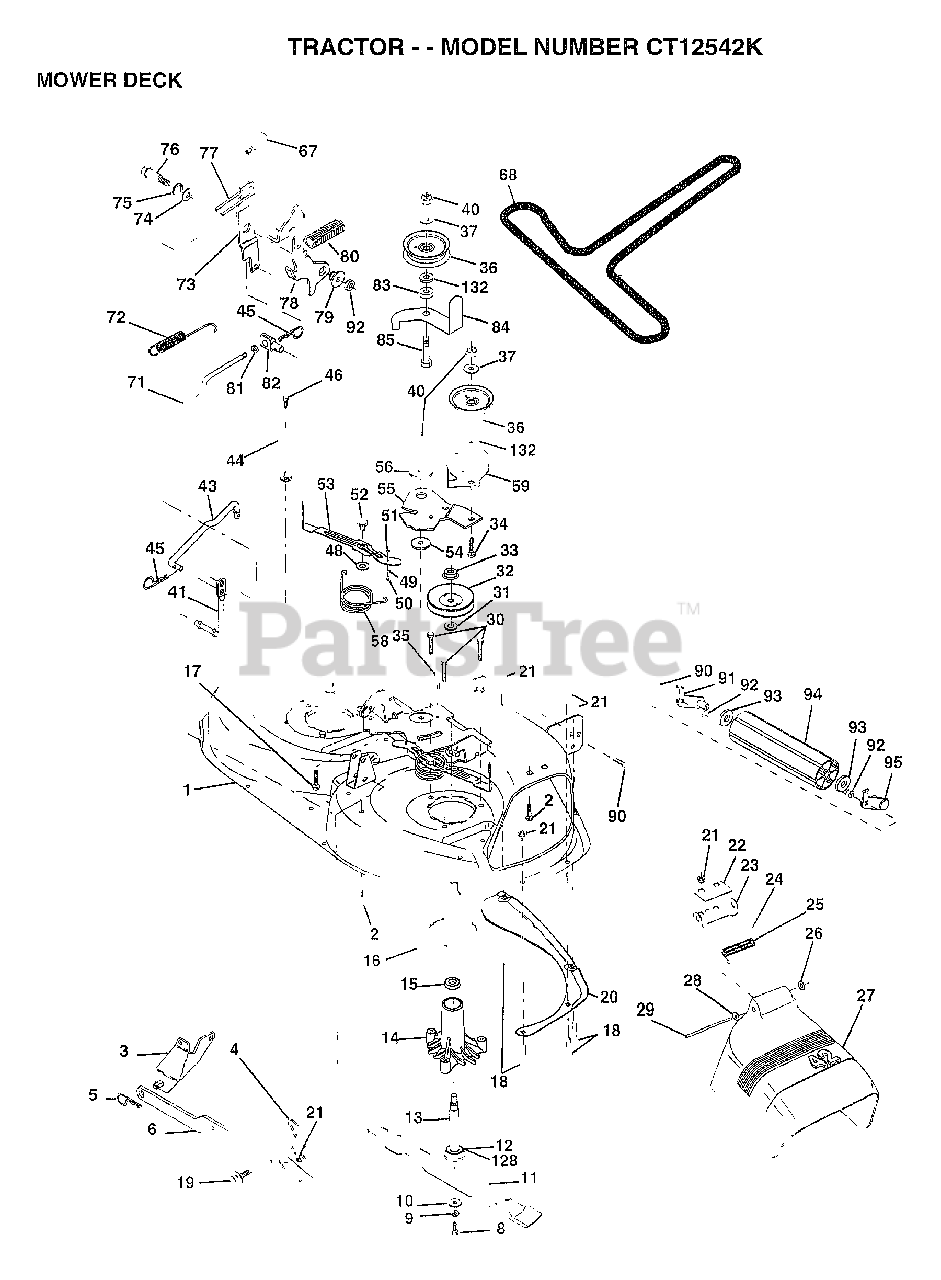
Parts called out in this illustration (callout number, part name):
1	DECK.WELD.42.
2	BOLT
3	BRKT ASM SWAY BAR
4	BRKT DECK SW BAR
8	BLADE BOLT
10	WASHER.HARD.BLADE
11	"BLADE.42"" HIPERF"
12	BEARING.BALL
14	HSG ASM MANDREL
15	BEARING
16	STRIPPER RND MWR
17	BOLT RDHD 3/8-16
18	BOLT
19	BOLT SHD 5/16-18
22	STIFFENER BRKT
23	DEFLECTOR BRKT
24	CAP-SLEEVE LT
25	SPRING TORSION
26	NUT PUSH M
27	DEFLECTOR.SHIELD
28	WASHER
29	HINGE ROD
31	WASHER
32	PULLEY.MANDREL.42
34	BOLT
35	XMAS TREE FASTNER
36	FLAT IDLER PULLEY
37	WASHER
41	PIVOT ROD
43	ROD CLUTCH W/NIBS
44	GUARD MAND LH BLK
46	SCREW.1/4-20X5/8
48	RETAINER M
48	HARD SMALL WASHER
49	ROLLER ASM-CAM
50	SHOULDER BOLT
51	LOCKNUT
52	BOLT.SHLD.5/16-18
53	BRAKE PAD ARM ASM
54	HARDENED WASHER
55	ARM-IDLER
56	SPACER RETAINER
58	SPRING TORSN BRAK
59	GUARD IDLER TUV
67	KNOB T(3/8 HOLE)
68	BELT.V.T-PATH
71	ROD CLUTCH 38/42
72	RETURN SPRING
73	CLUTCH ARM SECOND
74	WASHER
75	RING
76	SHOULDER BOLT
77	SPRING KEEPER
78	LEVER ASM-CLUTCH
79	BUSHING
80	SPRING.CLUTCH.MWR
81	NUT
82	TRUNION ADJ
83	WASHER
84	"KEEPER-BELT,FIXED"
85	BOLT RDHD 3/8-16
90	BOLT
92	NUT
93	WASHER
128	WASHER.FELT.
132	WASHER GT
